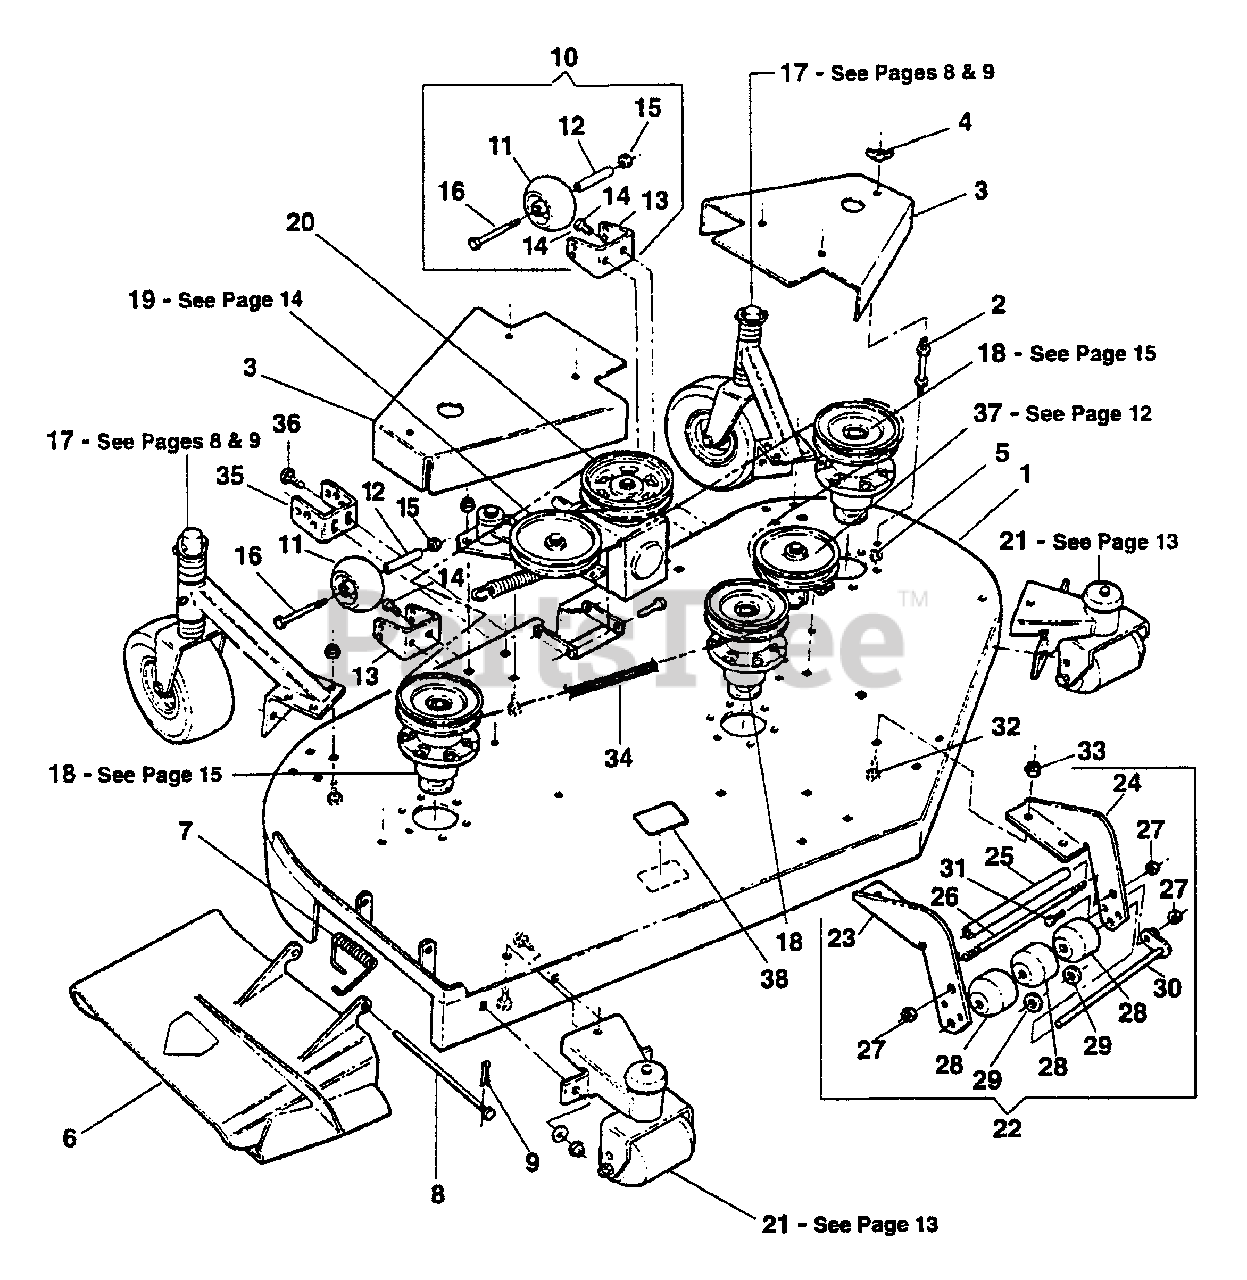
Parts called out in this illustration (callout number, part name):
1	WELDMENT, 73" OFZ MOWER DECK
2	STANDOFF, 3 1/2"
3	GUARD, Belt
4	WING NUT, 3/8-16
5	NUT, 3/8-16 HEX NYLON LOCK
6	DEFLECTOR, Chute, 73" Deck (Weldment)
7	SPRING, Chute
8	HINGE PIN, Chute
9	PIN, 3/32 x 1" Cotter
10	ASSEMBLY, Gage Wheel
11	WHEEL, Gage
12	SPACER, Gage Wheel
13	FORK, Gage Wheel
14	BOLT, 3/8-16 X 1" GD5 CZ
15	NUT, 1/2-13 Nyloc
16	BOLT, 1/2-13 X 5 GD5 YZ
17	GROUP, 9" Caster (Rear)
18	GROUP, Spindle
19	GROUP, Spring-Loaded Idler
20	GEARBOX, Right Angle
21	ASSEMBLY, Roller
22	ASSEMBLY, Center Deck Roller
23	MOUNT, Roller (R.H.)
24	MOUNT, Roller (L.H.)
25	ROLLER, Tube
26	ROD, Threaded Roller
27	NUT, 1/2-13 Nyloc
28	ROLLER, Low Density Poly
29	WASHER, 5/8" Flat
30	WELDMENT, Pivot Pin
31	BOLT, 1/2-13 X 1-1/2 GD5 CZ
32	BOLT, 3/8-16 x 1" Carriage, Grade 5
33	NUT, 3/8-16 HEX NYLON LOCK
34	BELT, 153" HB Section
35	BRACKET, Rear Deck Hanger
36	BOLT, 3/8-16 x 1" Carriage, Grade 5 (YZ)
37	GROUP, Fixed Idler
38	DECAL, 73 Deck
39	PULLEY 6.50 O.D.
